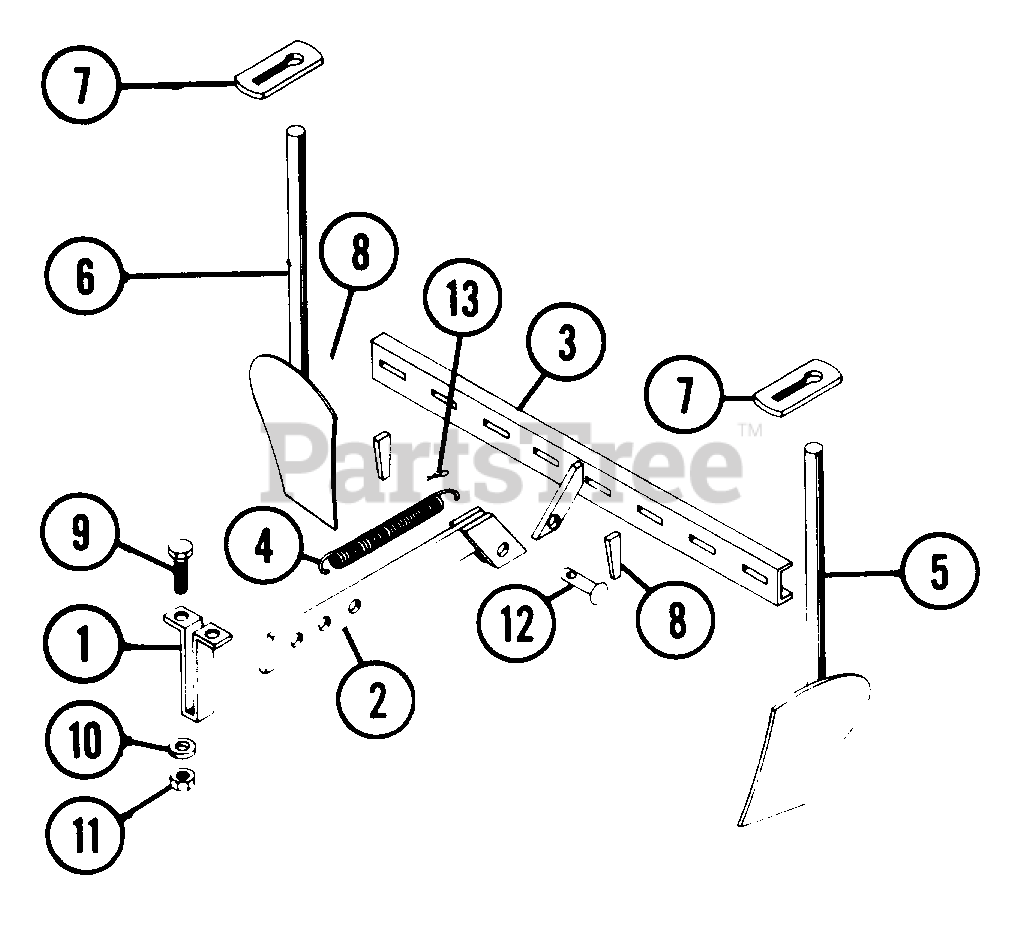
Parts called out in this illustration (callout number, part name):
2	STICK BRACKET
3	ATTACHING BAR
4	SG-TENS .060X.170X4.25 WLD ??
5	L H SHOVEL
6	R H SHOVEL
9	BLT-HEX .31-18X.75 PL GR2
10	WSHR-LK .313X.093 MED HICLR
11	NUT-HEX .312-18
12	CLEVIS PIN .437/.431X1.50 YWZC
13	PIN-HAIR INT .12X2.75
